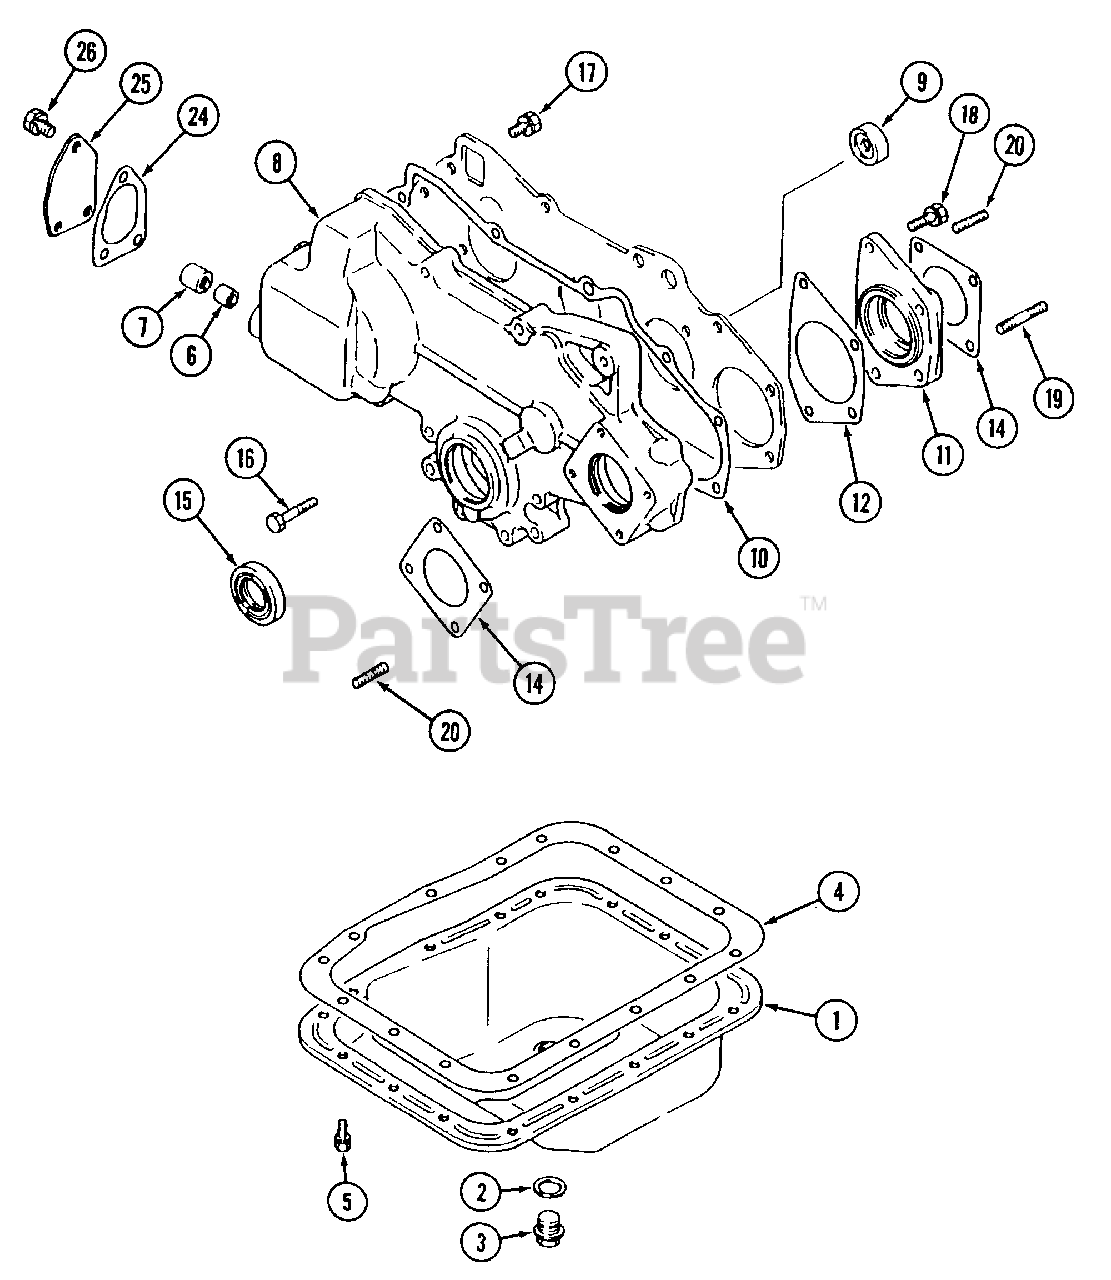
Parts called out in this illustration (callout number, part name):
1	Pan Ass'y., Oil
2	Gasket, Oil Drain Plug
3	Plug, Oil Drain
4	Gasket, Oil Pan
5	Bolt, w/Washer
6	Bearing, Needle
7	Bearing, Needle
9	Plug, Thrust
10	Gasket, Gear Case
11	Housing, Pump Gear Bearing
12	Gasket, Housing
14	Gasket, Oil Pump Cover
17	Bolt, w/Washer
18	Bolt, w/Washer
24	Gasket, Governor Cover
25	Cover, Governor
26	Bolt, w/Washer
